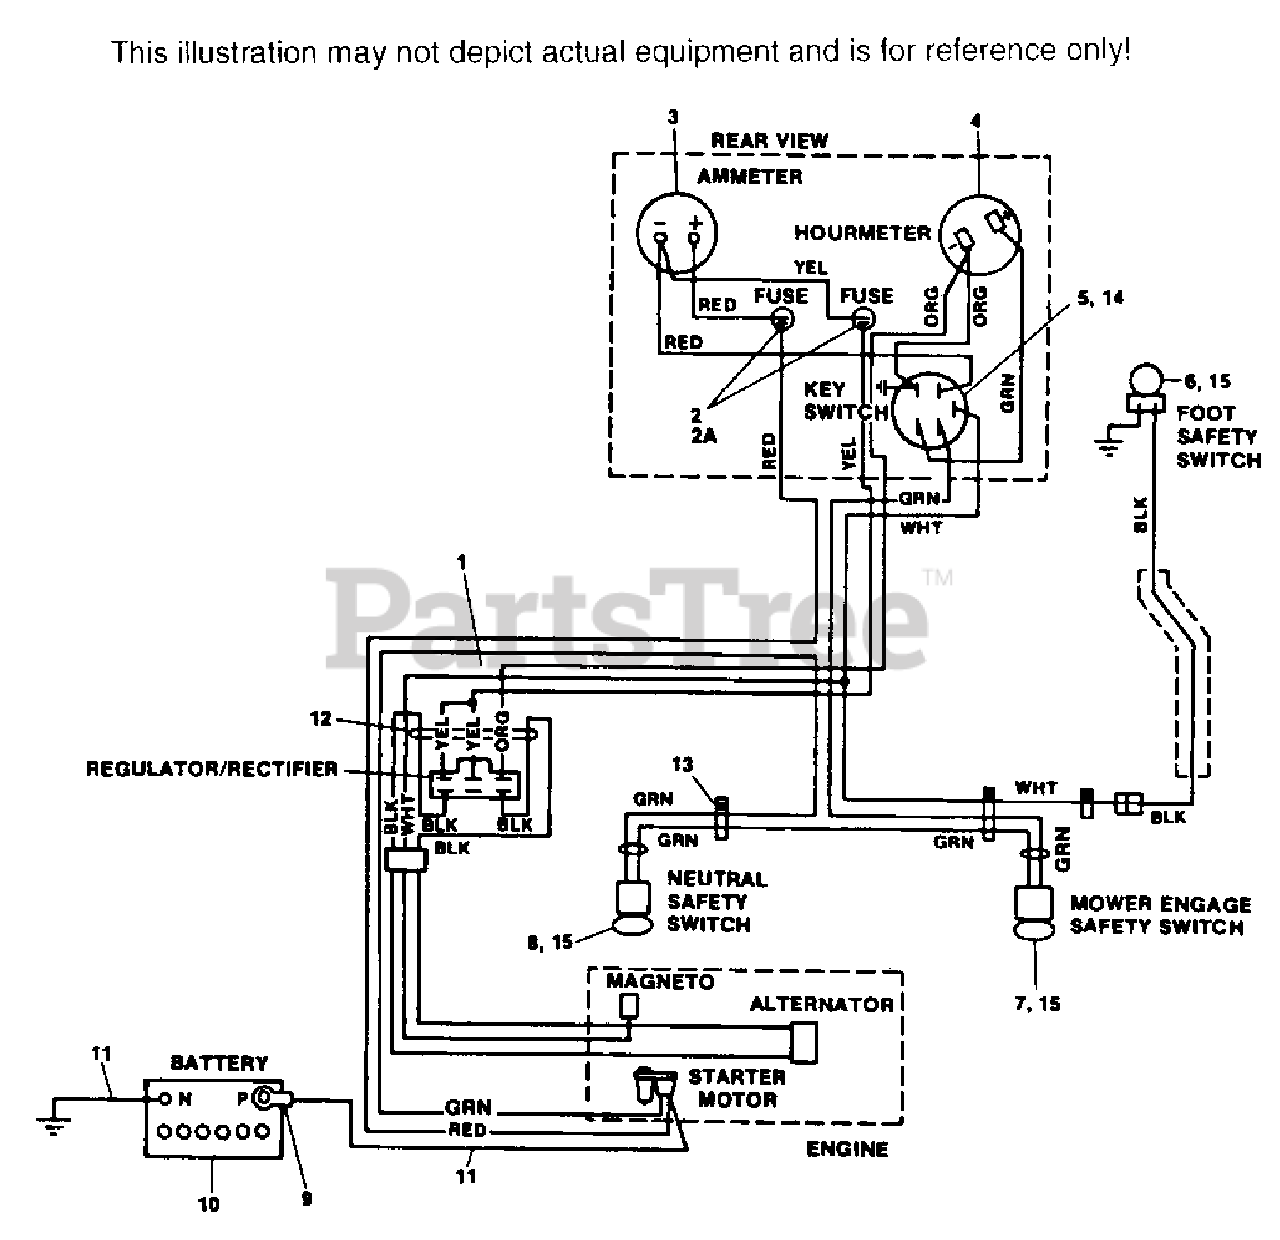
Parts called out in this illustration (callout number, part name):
1	WIRING HARNESS COMPLETE
2	FUSE HOLDER
2A	FUSE, 20A
3	AMMETER
4	HOUR METER
5	KEY SWITCH
6	FOOT SAFETY SWITCH
7	MOWER ENGAGE SAFETY SWITCH
8	NEUTRAL SAFETY SWITCH
9	RUBBER BOOT
10	BATTERY
11	BATTERY CABLE
12	CABLE TIE
13	CABLE CLAMP
14	CONNECTOR, STARTER SWITCH
15	CONNECTOR, SAFETY SWITCH
16	BATTERY CABLE, RED
